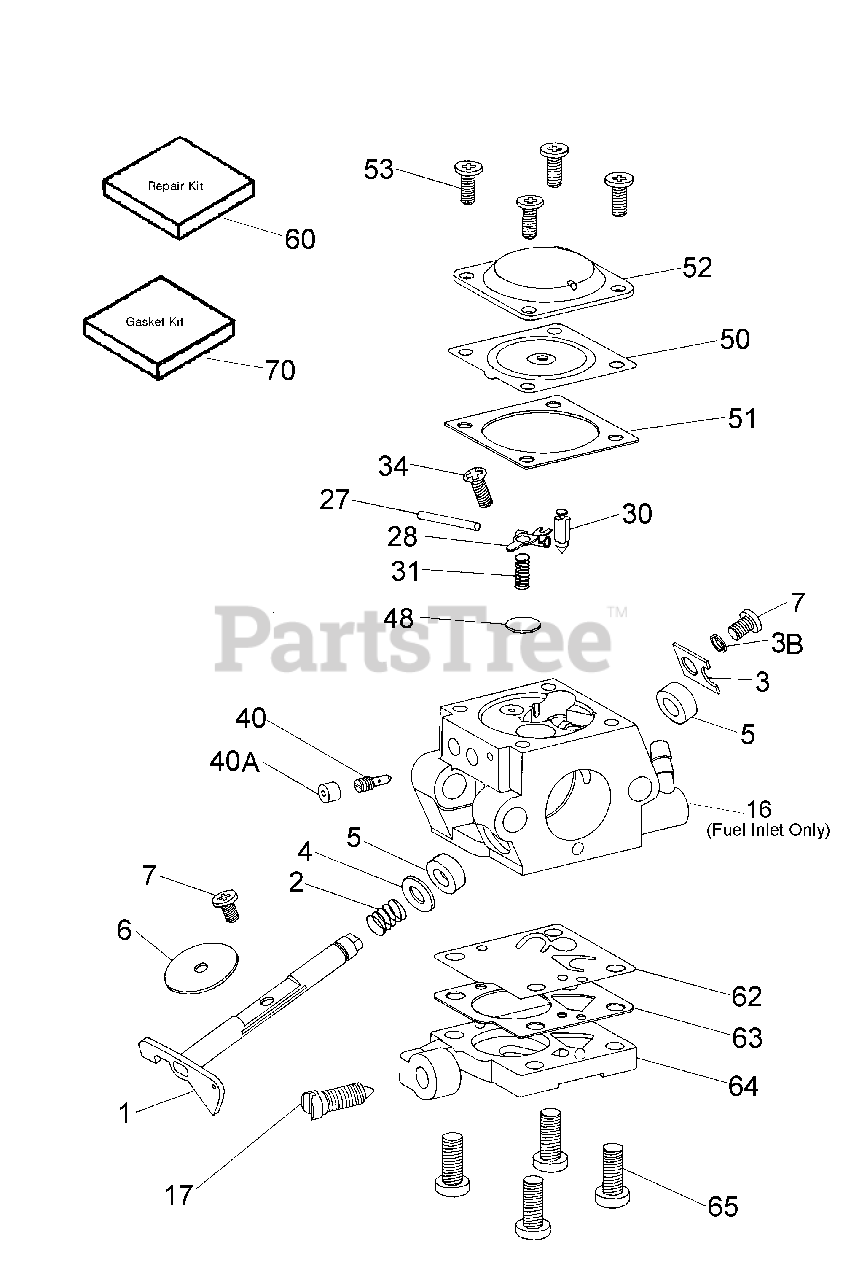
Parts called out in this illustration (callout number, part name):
1	Throttle Shaft & Lever Ass'y.
2	Throttle Return Spring
3	Dust Seal Retainer
4	Dust Seal Washer
5	Dust Seal
6	Throttle Shutter
7	Screw, Throttle Shutter & Dust Seal R etainer
16	Fuel Inlet (Plastic)
17	Idle Speed Screw
27	Hinge Pin
28	* Metering Lever
30	* Inlet Needle
31	Metering Lever Spring
34	Screw, Metering Lever Pin
40	High Speed Jet
40A	High Speed Jet Sealer Cap
50	Diaphragm (Included in Gasket Set)
51	Cover Gasket (Included in Gasket Set)
53	Cover Screw
60	Repair Kit (Incl. items marked PK in notes) Incl. (1) each of part #'s 640 242, 640243, 640257
62	Pump Diaphragm (Incl. in Gasket Set)
63	Pump Gasket (Included in Gasket Set)
64	Pump Cover
65	Pump Cover Screw
70	* Gasket Set Incl. (1) each of part #'s 640248, 640249, 640252, 640253
